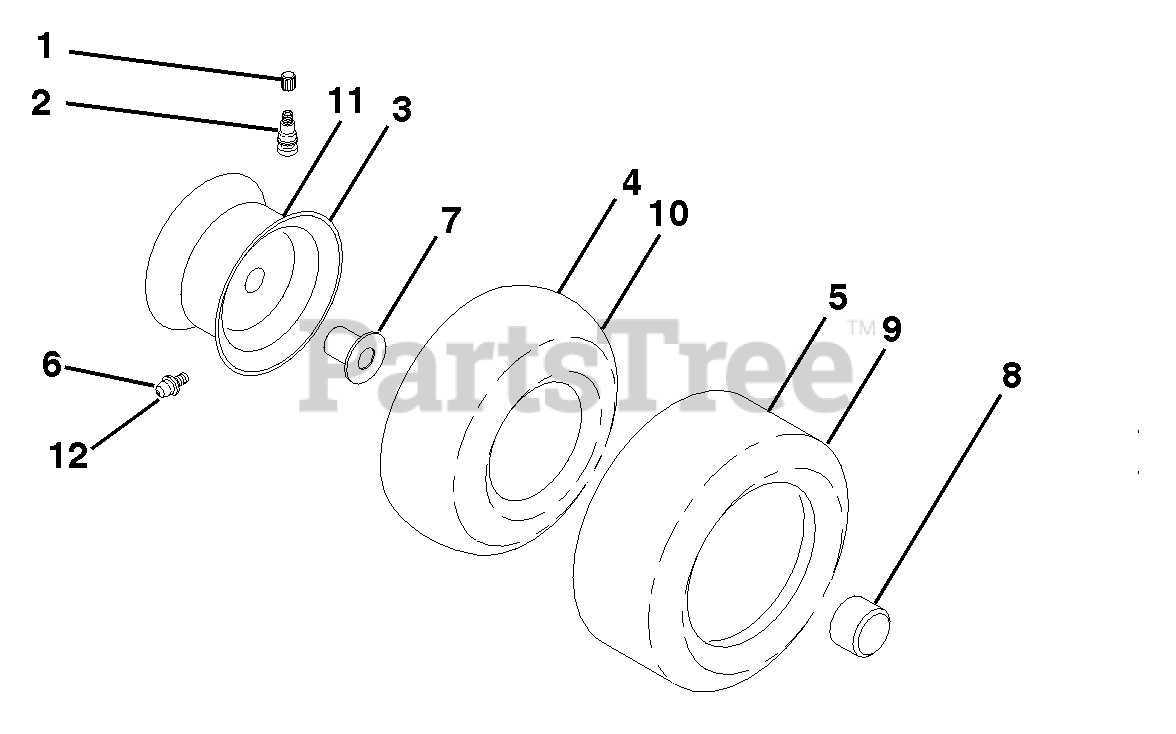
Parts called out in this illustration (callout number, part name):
1	Cap, Valve, Tire
2	Stem, Valve
3	Rim Assembly, Front
4	Tube, Front
5	Tire, Front
6	Fitting, Grease
7	Bearing, Flange
8	Cap, Hub, Axle Blk.
9	Tire, Rear
10	Tube, Rear
11	Rim Assembly, Rear
12	Fitting Grease
